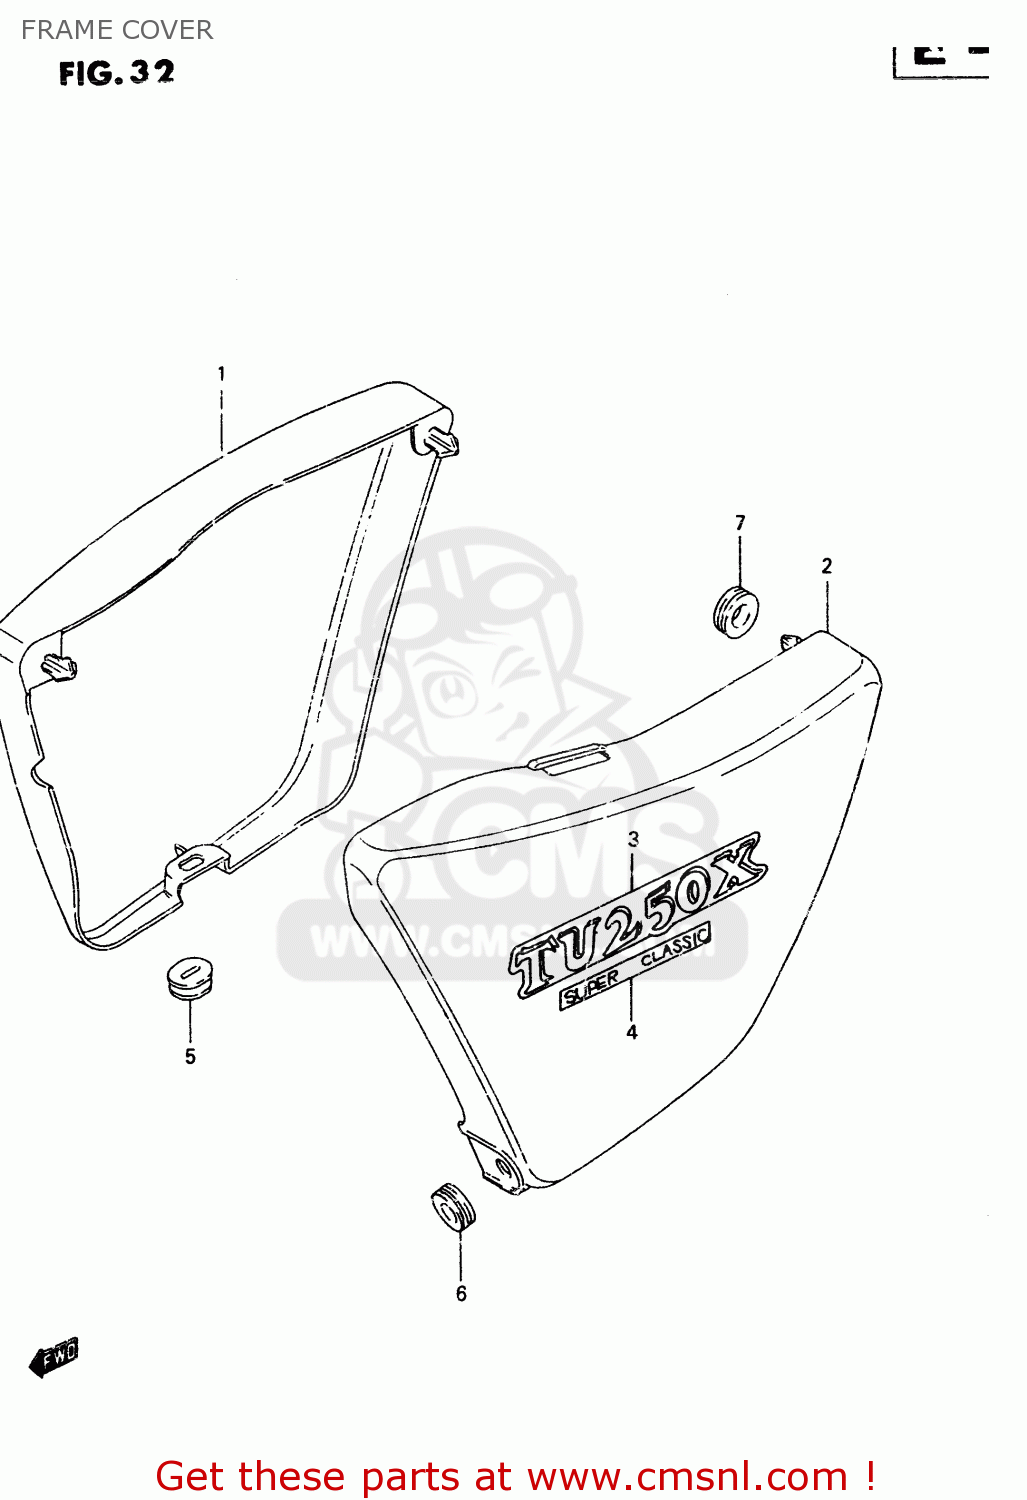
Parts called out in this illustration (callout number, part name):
1	COVER,FRAME,R(GREEN)
2	COVER,FRAME,L(GREEN)
3	EMBLEM,FRAME COVER,250X
4	EMBLEM,FRAME COVER
5	CUSHION
6	CUSHION
7	CUSHION
